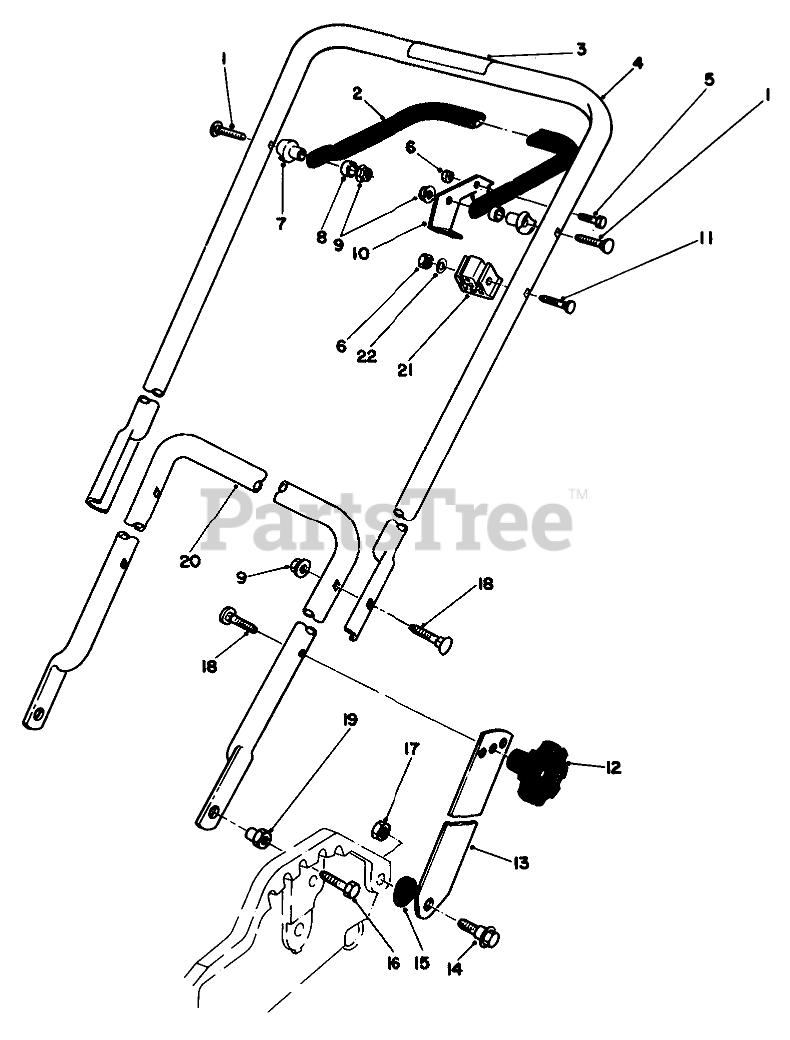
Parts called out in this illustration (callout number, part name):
1	5/16-18 X 2 HNDLE SCREW
2	Bar-Control
3	Decal-Danger
4	Handle-Upper
5	SCREW-HH
6	NUT-LOCK, NI
7	SPACER-SUPPORT
8	SPACER-NYLON
9	NUT-LOCK, NI
10	Lever-Control
11	HANDLE SCREW
13	Handle Latch
14	SCREW-SHOULDER
15	SPACER
16	SCREW-HH
17	NUT-LOCK, NI
18	SCREW
19	HANDLE PIVOT NUT
20	LOWER HANDLE
21	SUPPORT-CABLE
22	WASHER-FLAT
